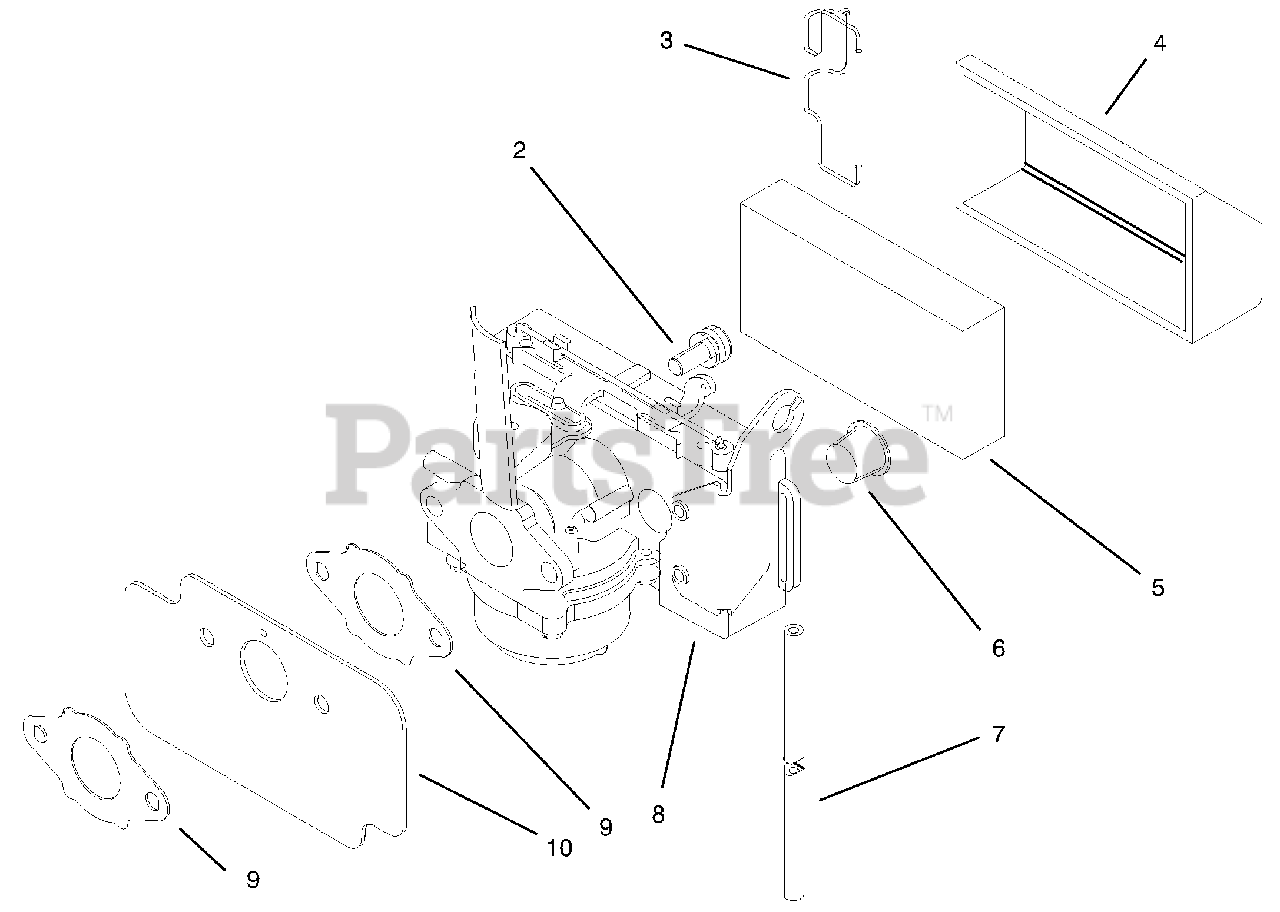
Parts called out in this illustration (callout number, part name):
3	Retainer-Filter
4	Cover-Air Cleaner
5	Element-Filter Air
6	Plug
7	Hose-Primer
8	Carburetor Assembly (Incl. Ref. #9)
9	Gasket-Carburetor
10	Shield-Carburetor
